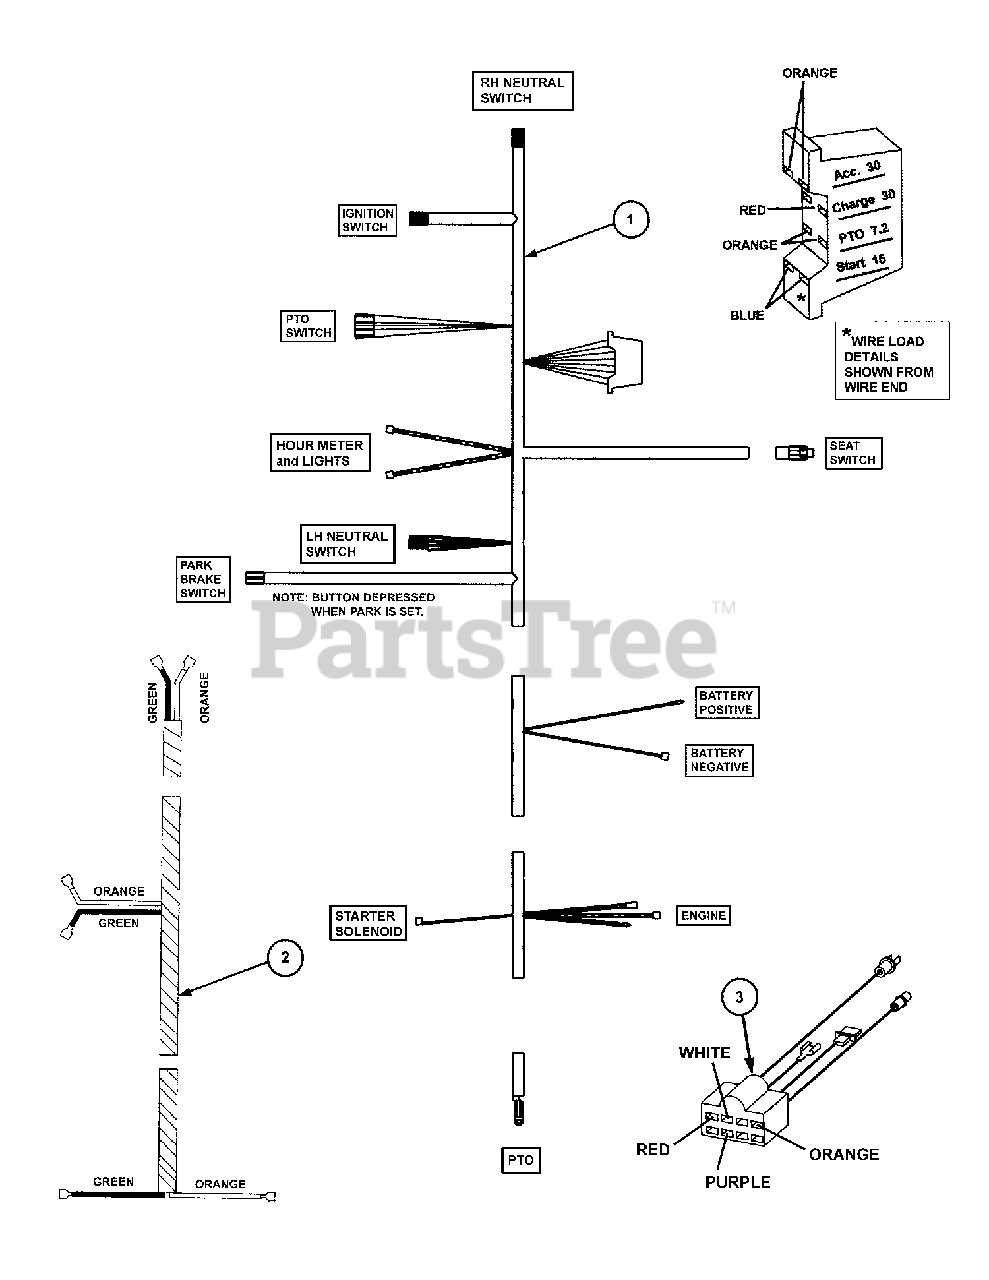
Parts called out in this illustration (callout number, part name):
1	WIRE HARNESS, Briggs 32 HP
2	WIRE HARNESS, Lights
3	WIRE HARNESS, Engine
